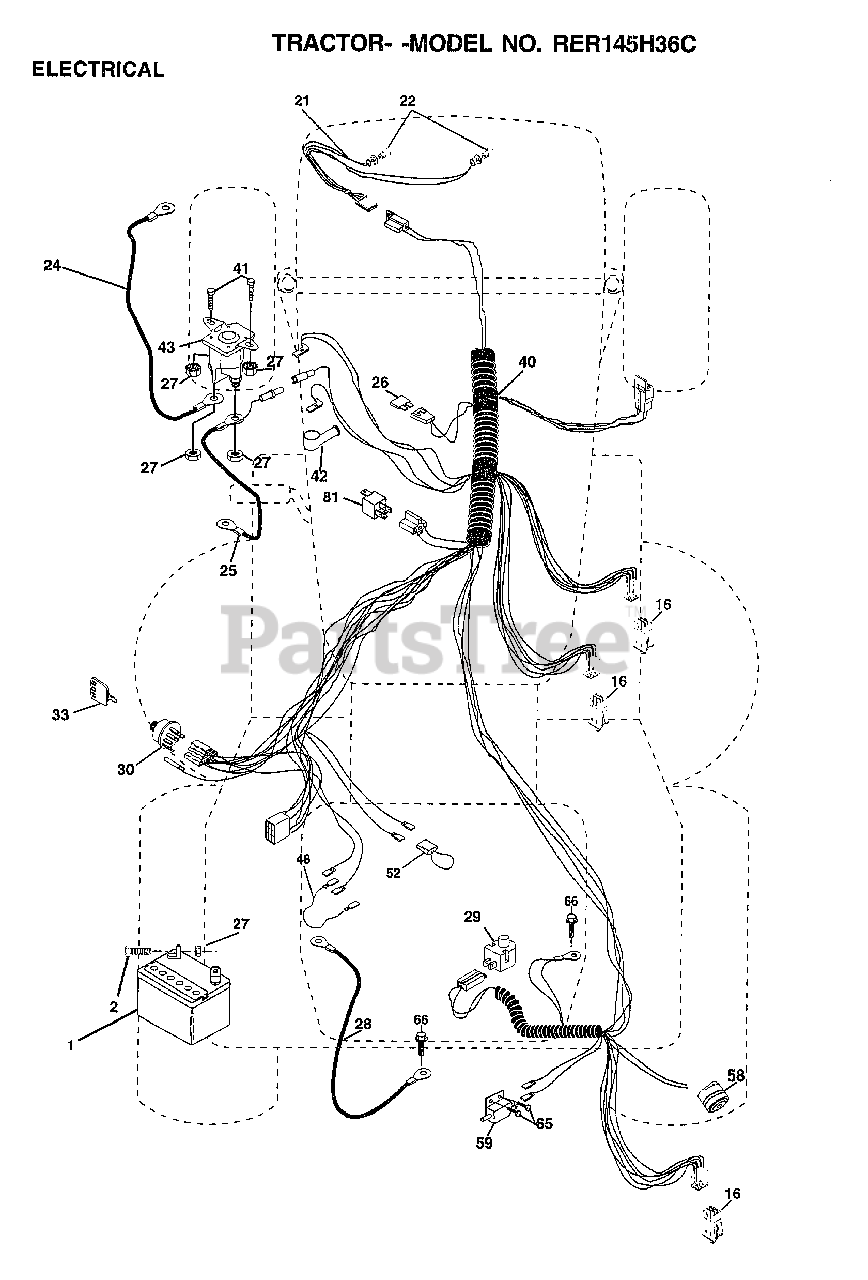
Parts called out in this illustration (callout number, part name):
2	BOLT LT
16	SWITCH INTERLOCK
21	HARNESS.ASM.LIGHT W/4152J
22	HEADLAMP BULB
24	"CABLE T, BATTERY"
25	CABLE.BATTERY.CRD
26	FUSE.15 AMP
27	NUT
28	"CABLE.GRD.6GA/18""BLACK"
29	SWITCH.PLUNGER
30	SWITCH.IGN.
33	KEY MLD GEN DELTA
40	HARNESS IGN CORD
41	BOLT HXHD FIN
48	ADAPTER AMMETER
52	PROTECTION LOOP
58	BUZZER CRD
59	SWITCH.FBI.CRD
65	SCREW
66	SCREW LT
81	RELAY ASSY T
